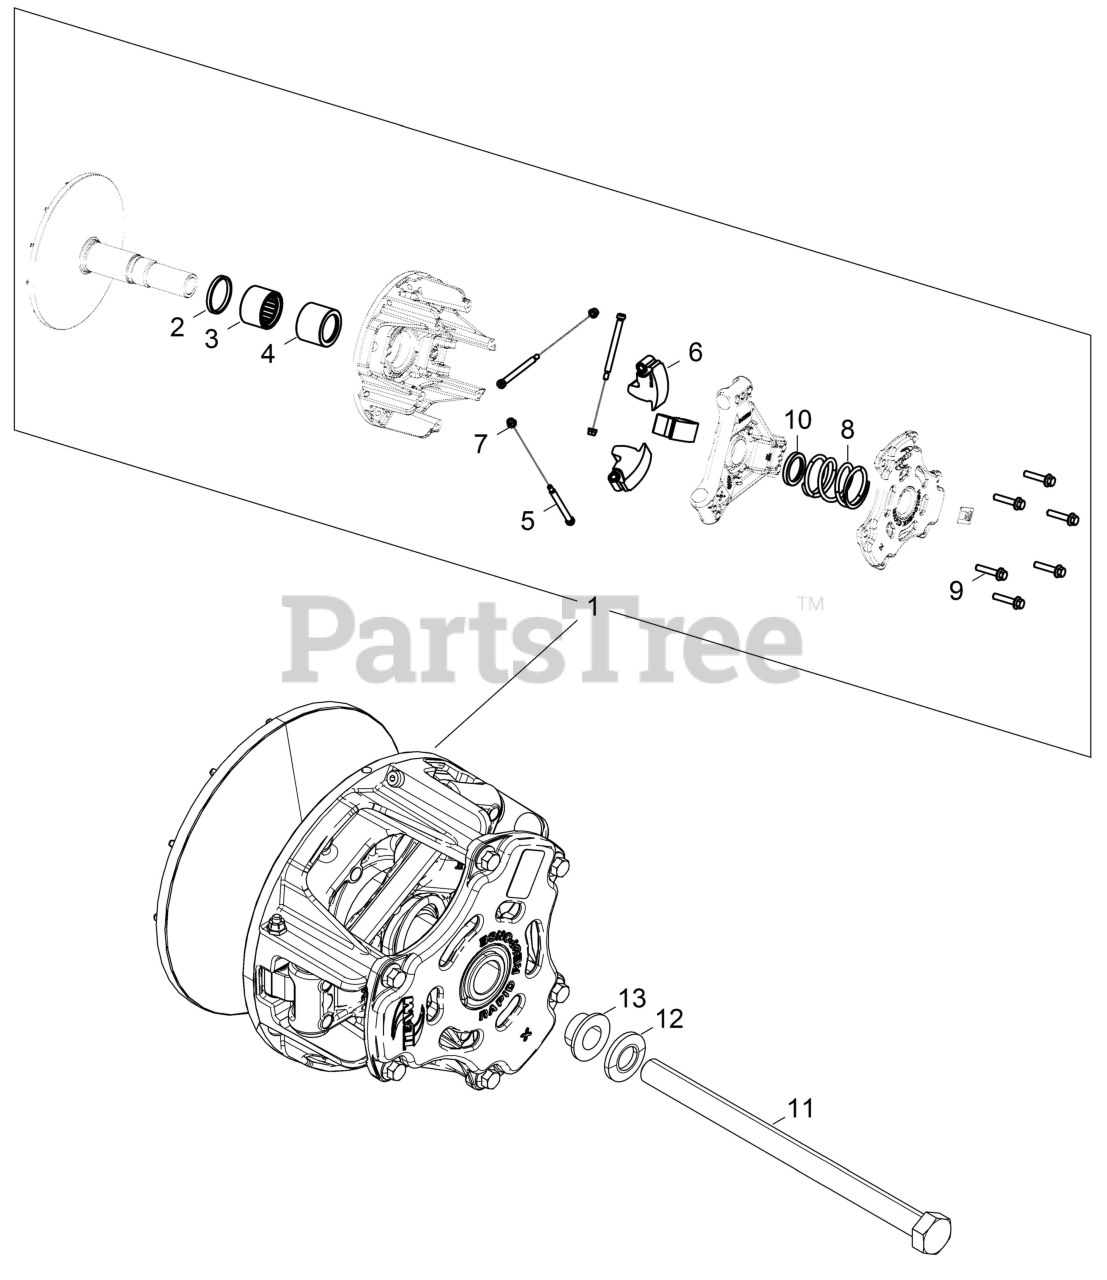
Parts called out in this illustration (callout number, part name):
1	ASM-DRIVE CLUTCH,DSL,35
2	WASHER, THRUST
3	SUBASSY-IDLER SLEEVE PRIMARY
4	CAP, IDLER SLEEVE
5	SCREW, SHOULDER HEX SKT .25 X
6	WEIGHT, CLUTCH, M17-198
7	NUT, LOCK HEX #10-24 FLEXLOC
8	SPRING, COMP.
9	SCREW, HEX FLANGE HD 1/4 - 20
10	SPACER, CLUTCH
11	SCR-M14X1.5X215, HX, 8.8
13	WASHER,CLUTCH RETAINER
